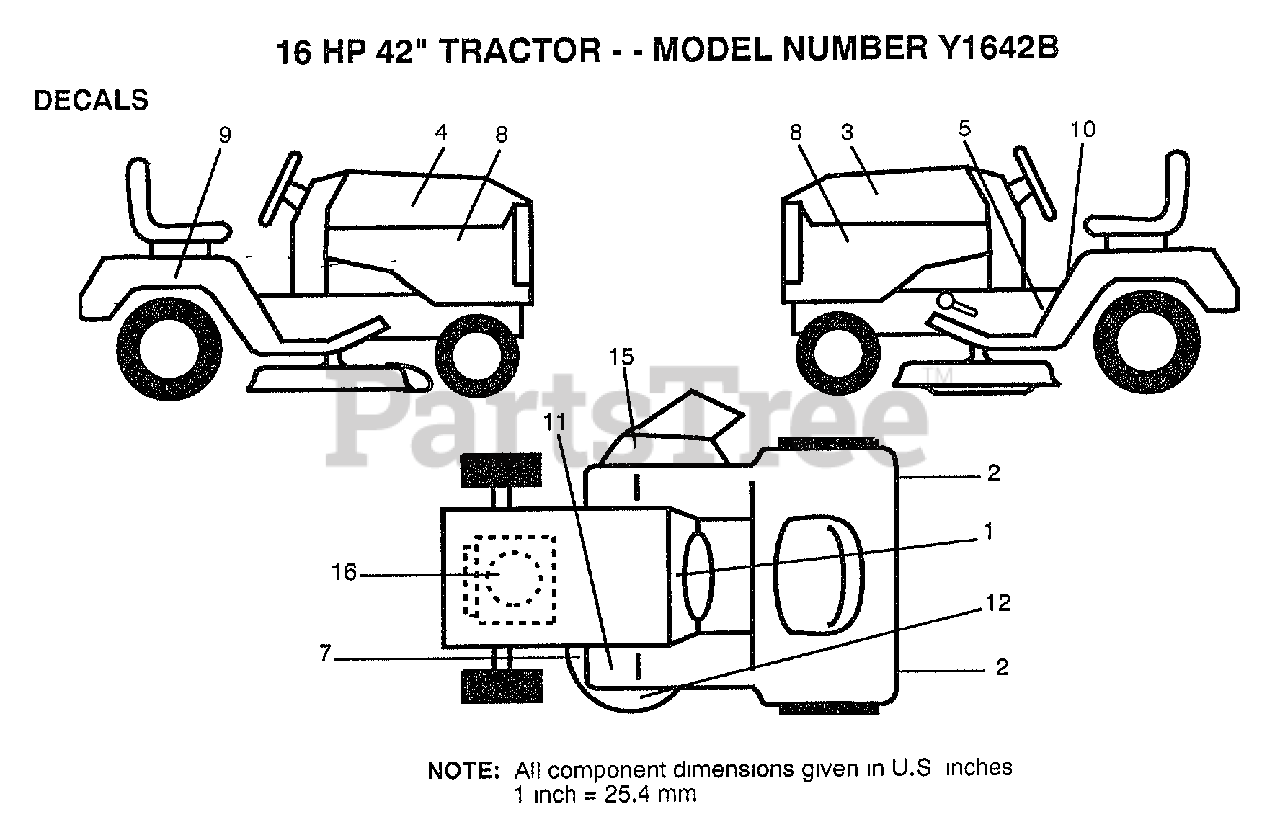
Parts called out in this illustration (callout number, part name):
1	DECAL.DASH.INSTR.
2	REFLECTOR-TAIL YT
3	DECAL HOOD LH
5	DECAL HANDLE LIFT
7	DECAL
8	DECAL.SIDE.PNL
10	DECAL CAUTION
11	DECAL T
15	"DECAL, WARNING"
